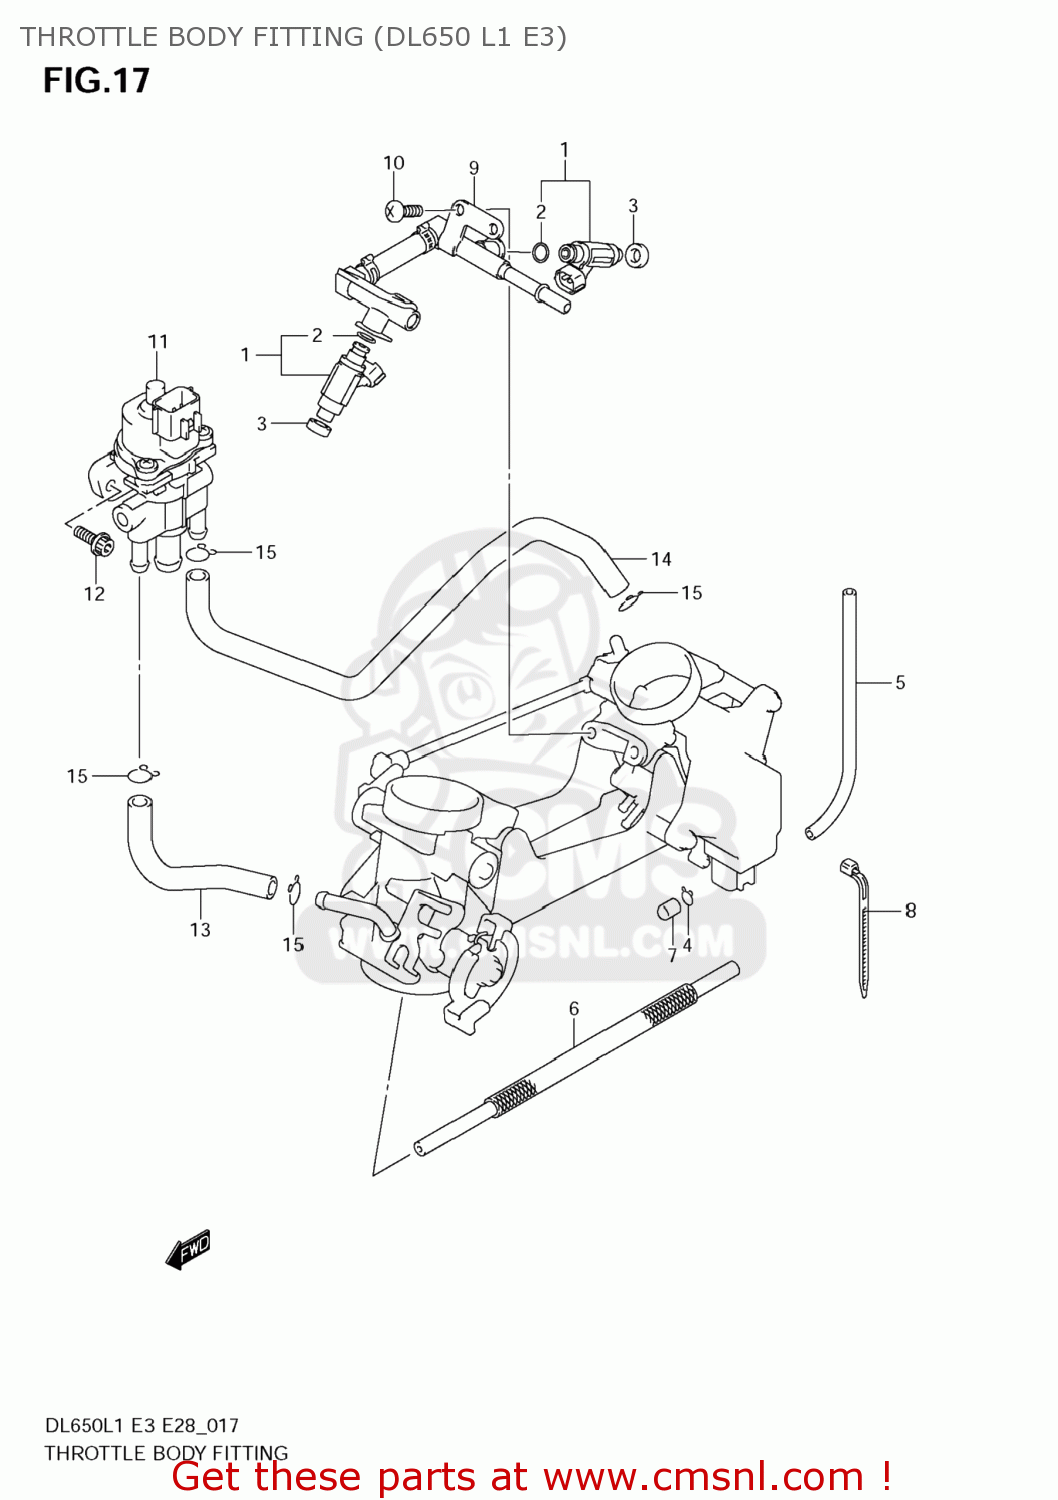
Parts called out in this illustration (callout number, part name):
1	INJECTOR ASSY
2	O RING
3	SEAL
4	CLIP
5	HOSE
6	HOSE
7	CAP
8	CLIP
9	DELIVERY PIPE ASSY
10	SCREW
11	VALVE,ISC
12	BOLT
13	HOSE,ISC VALVE FR
14	HOSE,ISC VALVE RR
15	CLIP
